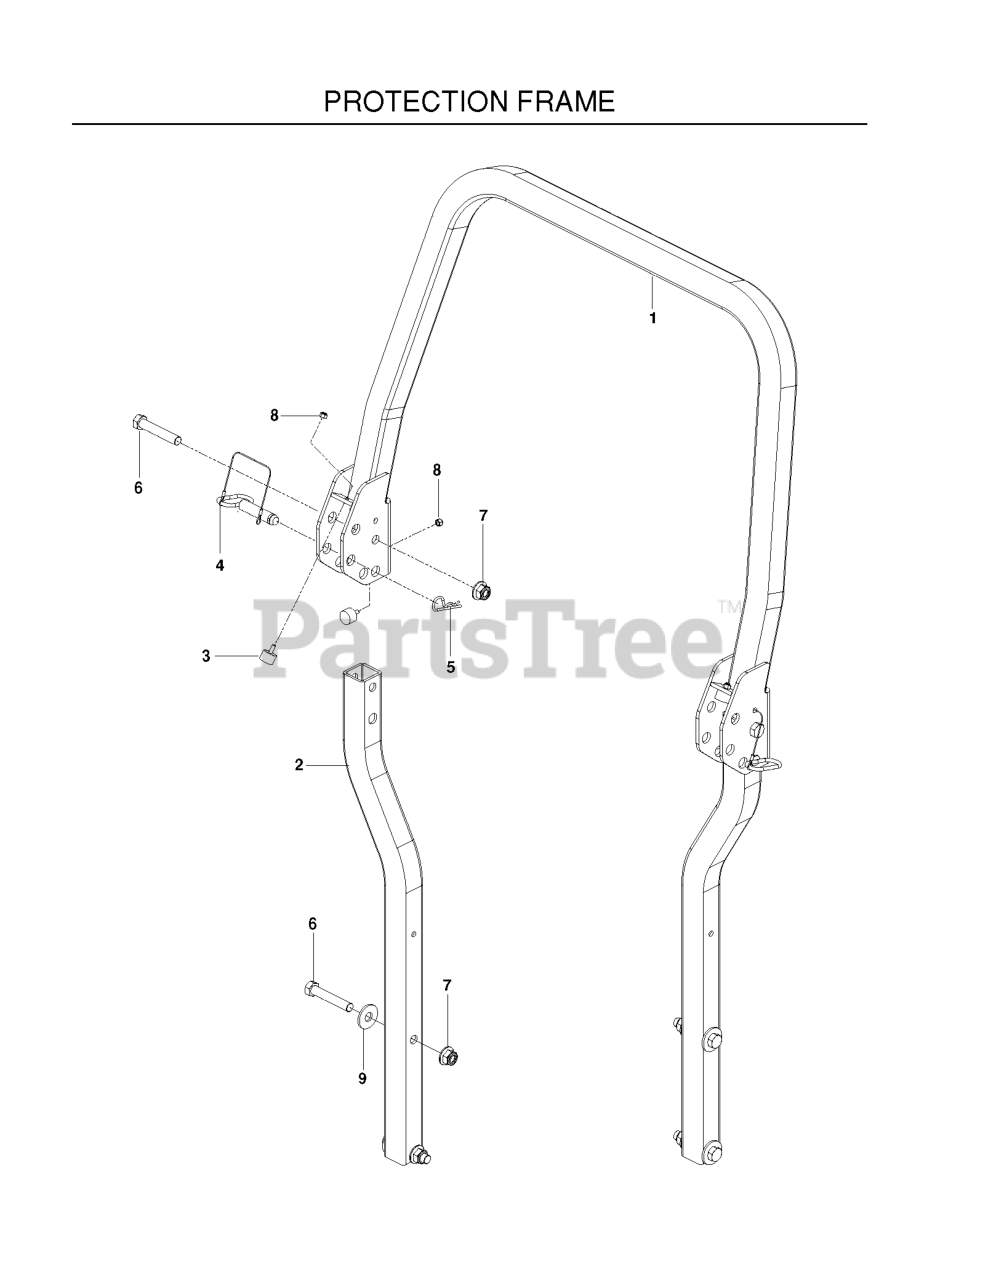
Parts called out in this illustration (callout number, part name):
1	ROPS.TOP.GRAY
2	TUBE.SIDE.ROPS.GREY
3	BUMPER, MALE STUD, 1/4-20
5	PIN HAIR .148 X 2-15/16 #210
6	5/8-11 X 3-1/2 HHB GRADE 5
7	NUT 5/8-11 FLG NYLOC ZD
8	NUT.1/4-20.HEX.NYLOC.ZD
9	WASHER, 5/8 FLAT
